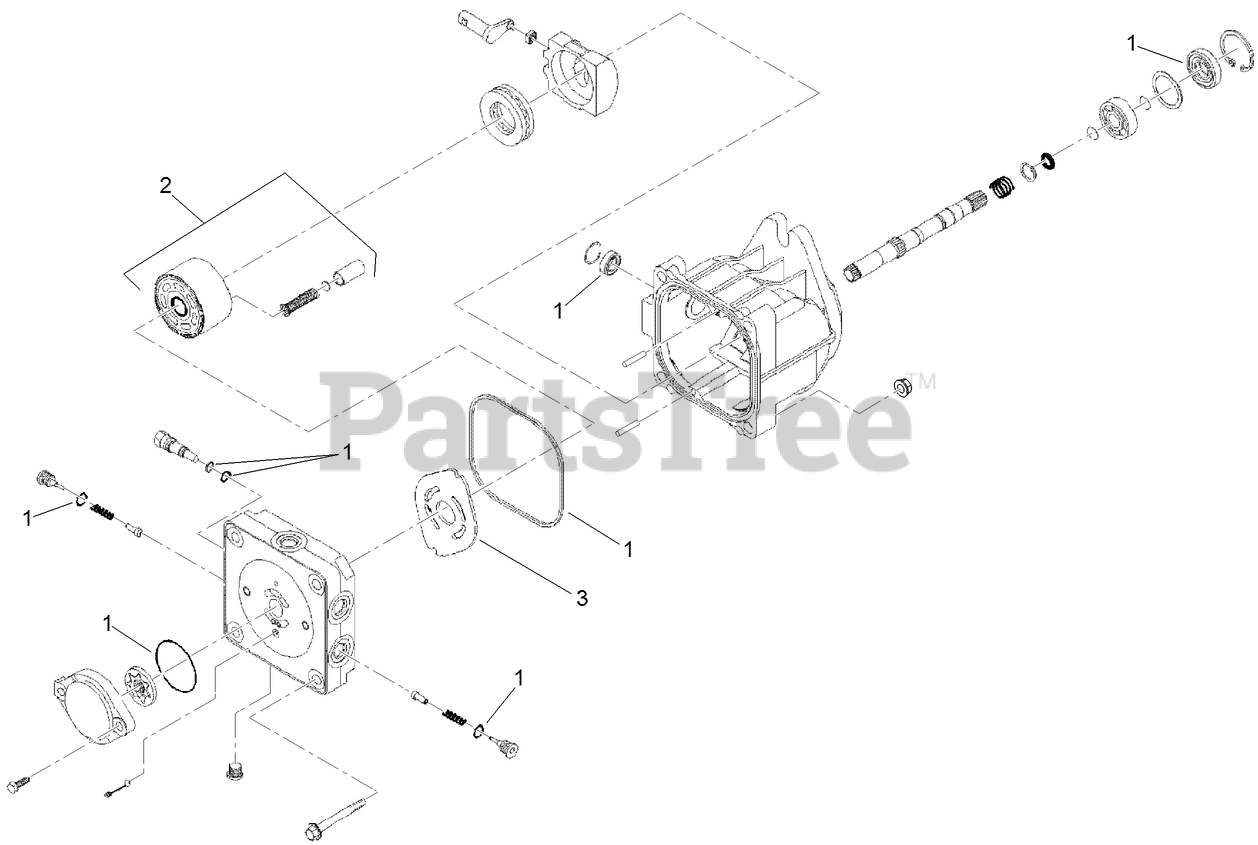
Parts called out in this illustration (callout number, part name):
1	OVERHAUL SEAL KIT
2	CYLINDER BLOCK ASM
3	PLATE-VALVE
